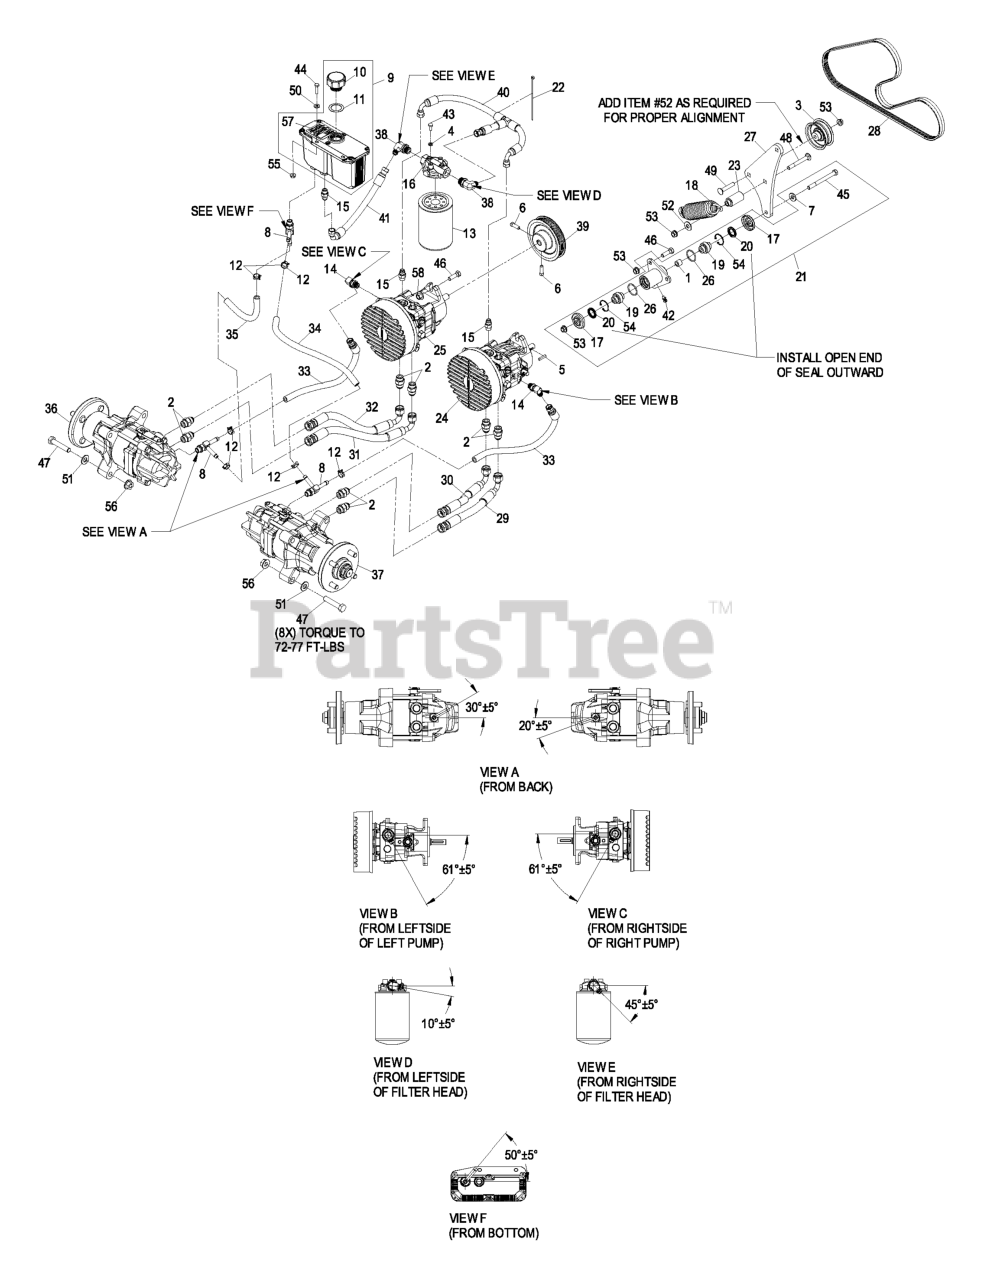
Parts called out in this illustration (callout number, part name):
1	BUSHING-LEVER, LIFT
2	FITTING-STRAIGHT
3	SHEAVE-IDLER
4	WASHER-LOCK
6	SCREW-SET
7	WASHER-BELLEVILLE
8	ADAPTER-RUN, TEE
9	HYD RESERVOIR ASM
10	Cap-Reservoir, HYD
11	GASKET-CAP
12	CLAMP-HOSE
13	FILTER,XP HYD 25 MICRON
14	FITTING-90 DEG
15	FITTING-STRAIGHT
16	HEAD-FILTER
17	GUARD-TOP
19	BEARING-SPHERICAL
20	SEAL-LIP, SINGLE
21	KIT,'04 XP PUMP IDLER
22	TIE-CABLE
23	SPACER, SPRING 1.75 (PLAT
25	PUMP,HYDRO PJ W/FAN RH
28	BELT,5K EL-54.50
29	HOSE,HYDRAULIC LH LOWER
30	HOSE,HYDRAULIC LH UPPER
31	HOSE,HYDRAULIC RH LOWER
32	HOSE,HYDRAULIC RH UPPER
33	ASM,CASE DRAIN
34	HOSE,CASE DRAIN LH
35	HOSE,CASE DRAIN RH
36	MOTOR,PRM18-RH
37	MOTOR,PRM18-LH
38	ADAPTER,90 DEG
39	SHEAVE,5K POLY-V
40	ASM,CHARGE HOSE TEE
41	ASM,CHARGE HOSE
42	FITTING-GREASE, 90 DEG
43	SCREW-HH
44	SCREW-HH
45	SCREW-HH
46	SCREW-HH
47	SCREW-HH
48	SCREW-CARR
49	SCREW-HH
50	WASHER-FLAT
51	WASHER-FLAT
52	WASHER-FLAT
53	NUT-HHF, WHIZ
54	RING-SNAP
56	NUT-HHF
58	NUT-FLANGE
